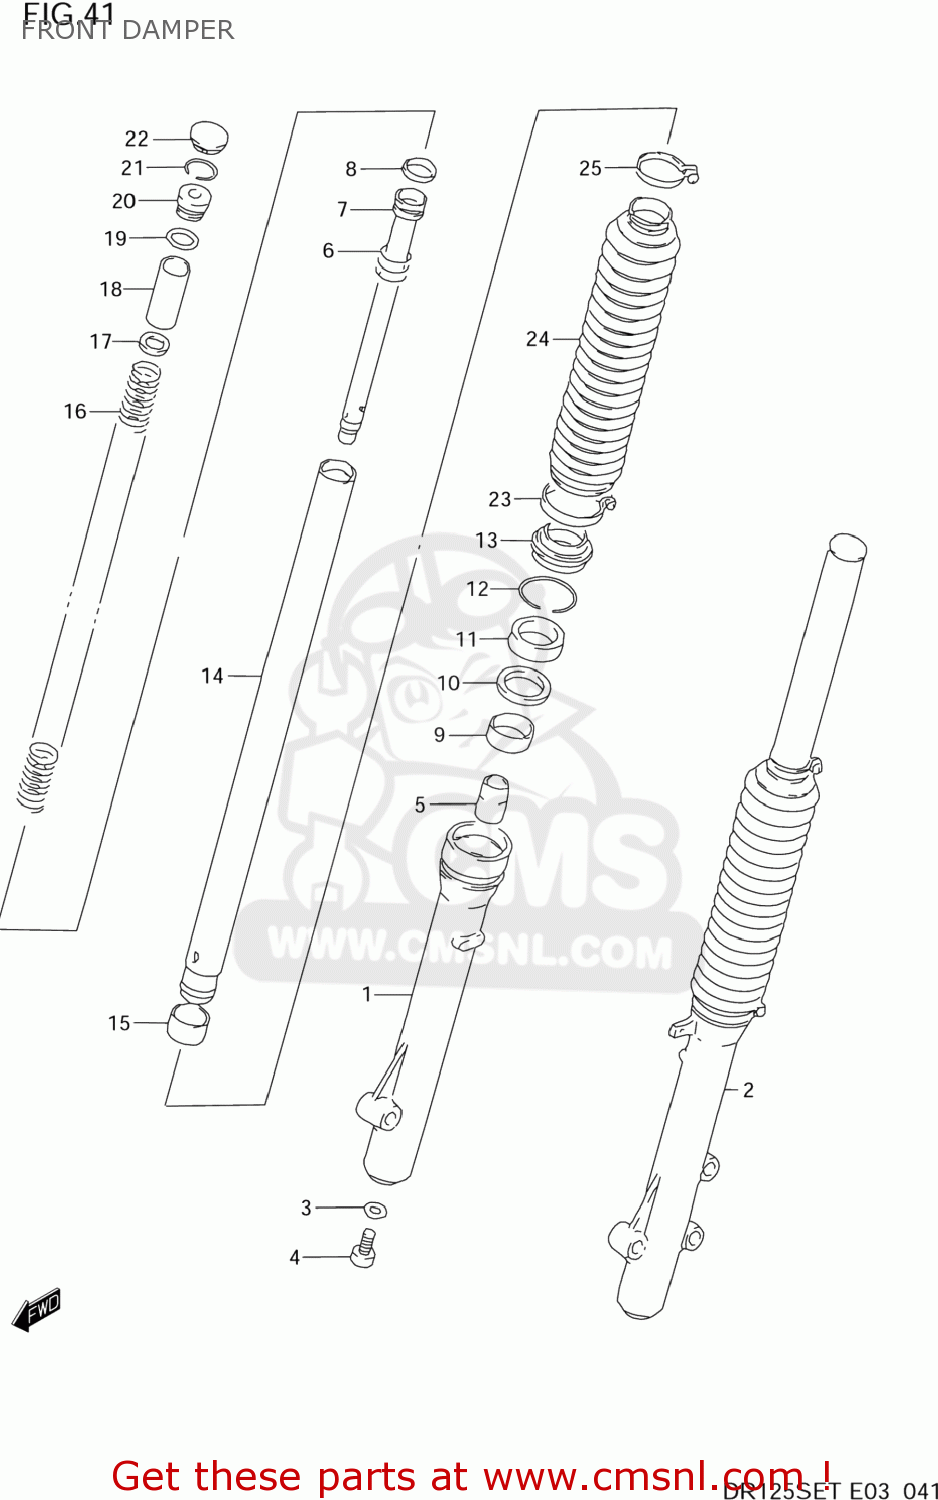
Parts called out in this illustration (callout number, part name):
1	TUBE,OUTER,R
2	TUBE,OUTER,L
3	GASKET (NAS)
4	BOLT,CENTER (8X18)
5	PIECE,OIL LOCK
6	SPRING,REBOUND
7	CYLINDER
8	RING,PISTON
9	BUSH,GUIDE
10	SPACER,SEAL
11	SEAL,OIL 35X48X11
12	RING,OIL SEAL STOPPER
13	SEAL,DUST
14	TUBE,INNER
15	PISTON
16	SPRING,MAIN
17	SPRING,JOINT
18	SPACER,SPRING
19	O RING
20	SPRING SEAT B
21	RING,STOPPER
22	CAP
23	BAND,BOOT LWR
24	BOOT
25	BAND
